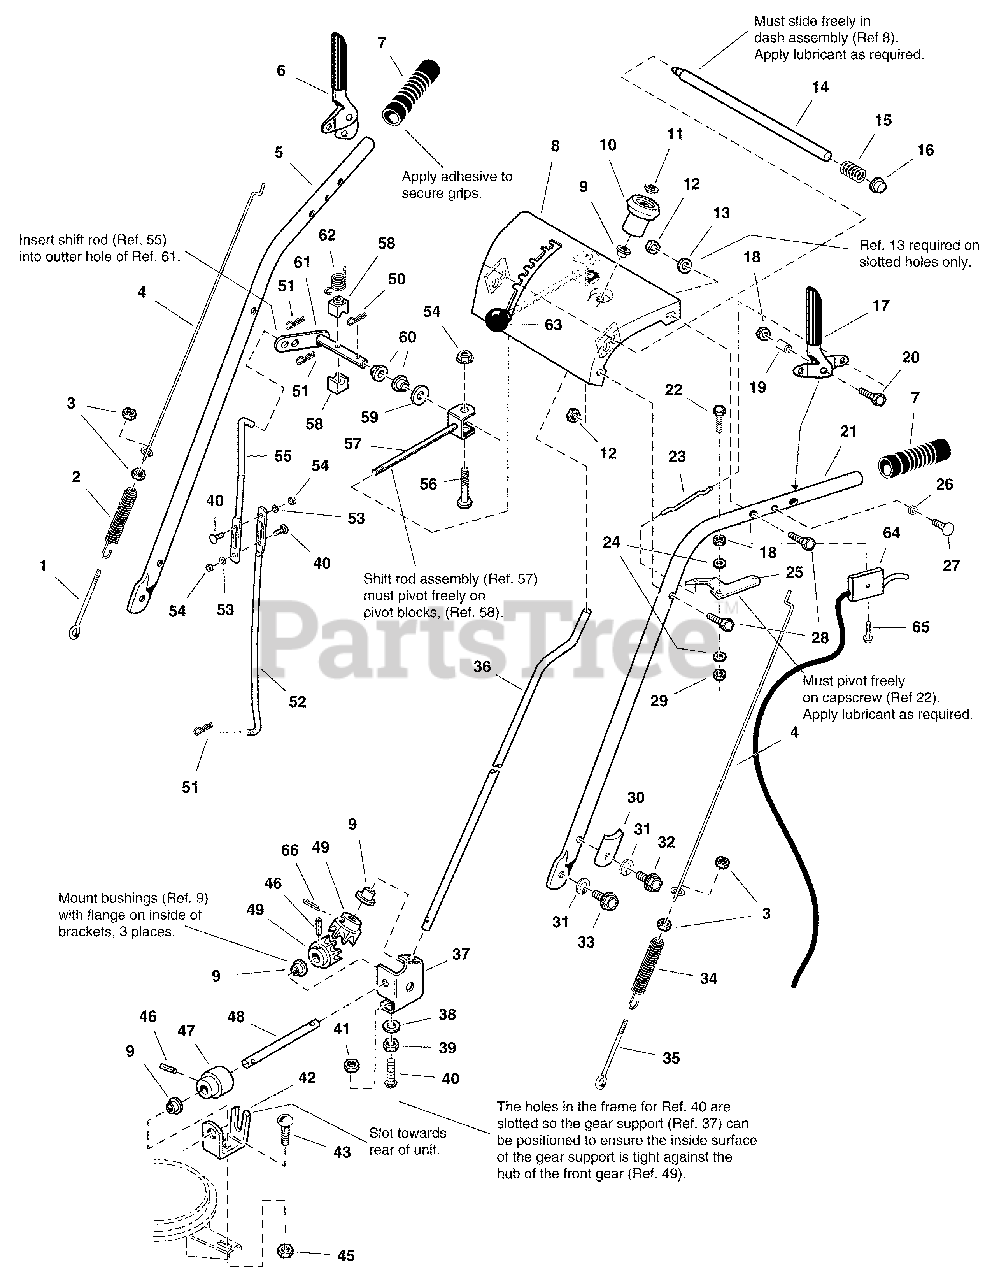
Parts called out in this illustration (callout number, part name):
1	ROD, Auger, 3 7/16 Long 10-24
2	SPRING, Extension, 3 7/16 Long
3	NUT, Hex Machine Screw, 10-24
4	ROD, Clutch/Traction, 23 1/8 Long
5	HANDLE, RH
6	HANDLE, Clutch, RH
7	GRIP, Black Vinyl
8	DASHBOARD & SUPPORT ASSEMBLY
9	BUSHING, 3/8
10	KNOB, Spinner, 2 1/2 Long
11	PUSH NUT, Pal, 3/8
12	NUT, ESNA Flange 5/16-18
13	WASHER, 5/16
14	ROD & SPRING ASSEMBLY, with Pin
15	SPRING, Compression, 1 7/8 Long
16	PUSH NUT, Stud Cap, 1/2
17	HANDLE, Clutch, LH
18	NUT, Hex Centerlock, 1/4-20
20	CAPSCREW, Hex Head, 1/4-20 x 1 1/2
21	HANDLE, LH
22	CAPSCREW Hex Head, 1/4-20 x 2
23	ROD, 5 3/4 Long
24	WASHER, 1/4
25	LEVER, Pivot
27	SCREW, Taptite, Pan Head, Torx, 1/4-20 x 3/4
28	CAPSCREW, Hex Head, 5/16 x 1 1/2
29	NUT, Hex Lock ESNA Light, 1/4-20
30	CLAMP, Tube Saddle
31	LOCKWASHER, Spring, 5/16
32	CAPSCREW, Hex Head, 5/16-18 x 1 3/4
33	CAPSCREW, Hex Head, 5/16-18 x 3/4
34	SPRING, Extension, Clutch Rod
35	ROD, Clutch, 6 5/16 Long
36	ROD, Chute Control, 27 Long
37	SUPPORT, Gear
38	WASHER, 1/4
39	PUSH NUT, 1/4
40	CARRIAGE BOLT, 1/4-20 x 5/8 G5
41	NUT, Hex Whiz Lock Flange, Small, 1/4-20
42	SUPPORT, Worm
43	CARRIAGE BOLT, 5/16 x 3/4 G5
45	NUT, KEPS, 5/16-18
46	PIN, Spring 1/8 x 3/4
47	WORM, Chute, LH
48	ROD, Chute, 18 Long
49	GEAR, Powder Metal
50	PIN, Hair
51	PIN, Hair
52	ROD, Shift, 3/8 15 5/16
53	LOCKWASHER, Spring, 1/4
54	NUT, Hex Flange ESNA, 1/4-20 Yellow
55	ROD, Upper Shift, 12 1/2 Long
56	CAPSCREW, Hex Head Whize Lock Flange, 1/4-20 x 2-1/4 G5 Black
57	ROD & CLEVIS ASSEMBLY, Shift
58	BLOCK, Pivot, 3/4 x 3/4
59	WASHER, 1/2
60	BUSHING, 1/2
61	ROD & ARM ASSEMBLY, Pivot
62	SPRING, Torsion, 1/2 Long
63	KNOB
64	CABLE & HANDLE ASSEMBLY
65	SCREW, Pan Head, Torx, #10 x 1/2
66	PIN, Cotter 1/8 x 1 LG
